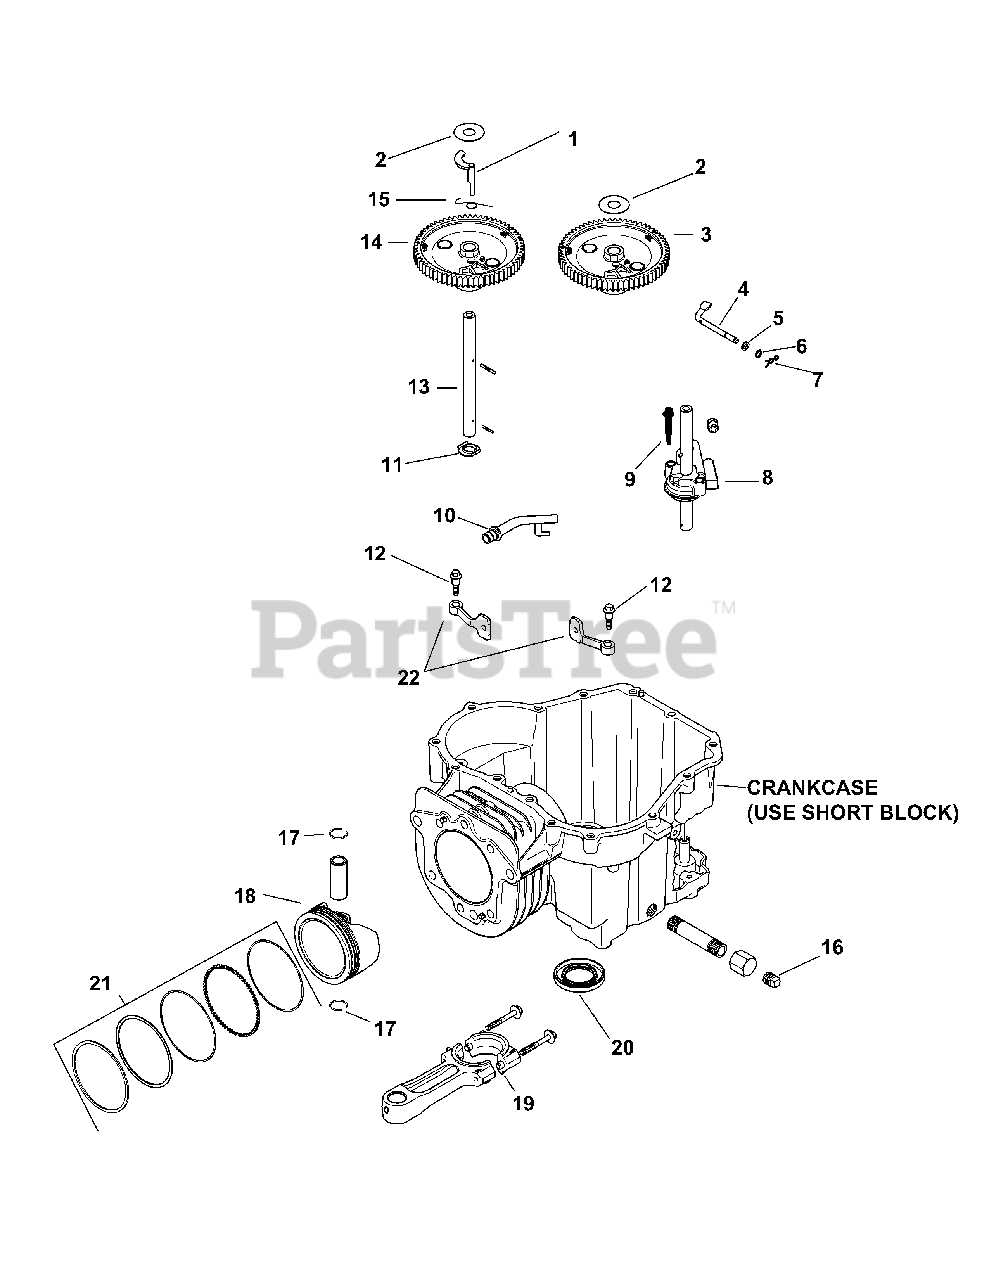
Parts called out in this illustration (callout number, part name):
2	Thrust -Acr. Washer
3	Cam Gear Assembly, Intake
4	Governor Cross Shaft
5	Flat Washer, 6 Mm
6	Flat Washer, 1/4
7	Hitch Pin Clip
8	Oil Pump Ass’y Kit
9	Oil Pump Screw
10	Drainback Tube
11	Thrust Washer
12	Shd. Thd. Frm. Screw, M6 X 1 X 26
13	Cam Center Shaft Kit
14	Cam Gear Assembly
16	Square Head Pipe Plug, 3/8
17	Piston Pin Retainer
18	Piston w/ Ring Set, 94mm
19	Connecting Assembly Rod
21	Ring Set (94mm)
22	Cam Lever Kit
